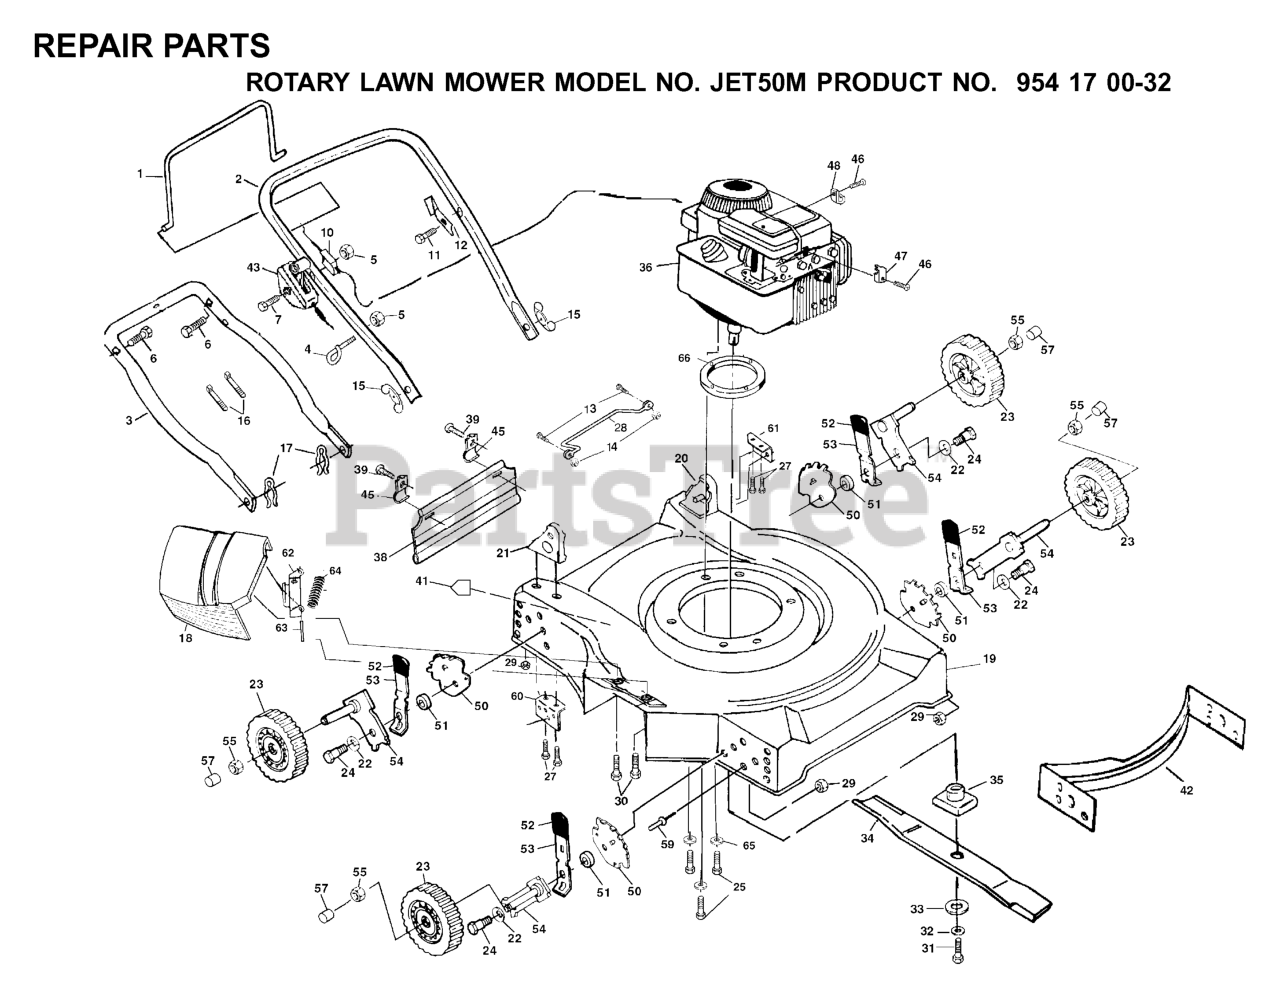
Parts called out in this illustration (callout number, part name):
1	CONTROL BAR
3	HANDLE, LOWER
4	ROPE GUIDE
5	NUT
6	HANDLE BOLT
7	SCREW.PAN.HEAD
10	CABLE.MZR.51.RT.SP./PU.
11	TAPPING SCREW
12	BRACKET UPSTOP
13	REPL BY 817 02 10-08
15	NUT WING PM
16	TIE GUIDE
17	HAIRPIN COTTER
20	HANDLE BRACKET ASM. LH
21	HANDLE BRACKET ASM. RH
22	WASHER.BELLEVILLE (3 2 LB)
23	WHEEL
24	BOLT
27	SCREW.5/16-18X3/4
29	LOCKNUT PM
31	SCREW, HEX HD 3/8-24 X 1-3/8
32	LOCKWASHER
33	WASHER,HARDEN
35	BLADE ADAPTOR
38	REAR SKIRT
39	TAPPING SCREW
41	DECAL MOWER CUT/FINGER
43	THROTTLE CONTROL
45	BRACKET DEFL PM
46	SCREW.HEX.HEAD.WASHER.10-16
47	CABLE CLAMP(ENGINE)
48	GUIDE CLIP PM
50	WHEEL ADJUST BRACKET
51	RP SPACER HT ADJ
53	SELECTOR SPRING
54	AXLE, REAR
55	HEX FLANGE LOCKNT
59	RIVET BLIND
60	REPL BY 532 12 52-05
62	BRACKET PM
63	ROD.HINGE.COMBI-C
